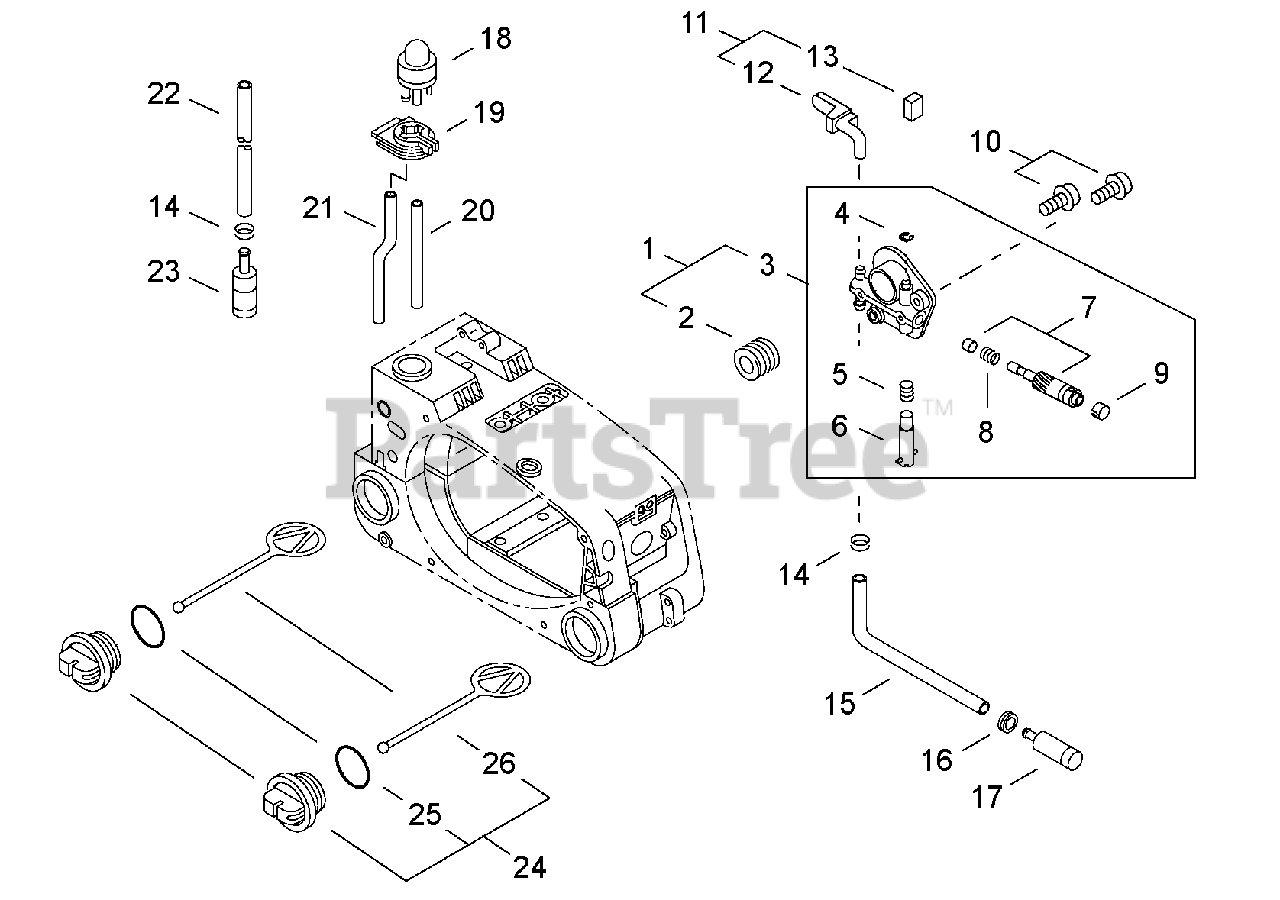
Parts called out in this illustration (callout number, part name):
1	AUTO-OILER ASSY, & WORM GEAR
2	GEAR, WORM
3	AUTO-OILER ASSY
6	ADJUSTER, OILER
7	PLUNGER ASSY
9	CAP, PLUNGER
10	SCREW 5×12
11	PIPE KIT, OIL
12	PIPE, OIL OUTLET
13	PAD, FOAM
14	CLIP Ø6.5 MM
15	PIPE 3×6×115 BLACK
16	GROMMET
17	FILTER, OIL
18	BULB, PURGE
19	BRACKET, BULB
20	PIPE, FUEL 3x-5x-70 BLACK
21	PIPE, FUEL 2×4×42 CLEAR
22	PIPE, FUEL 3×6×160
23	FILTER, FUEL
24	CAP ASSY
25	O-RING 25
26	CONNECTOR, CAP L= 60 MM
